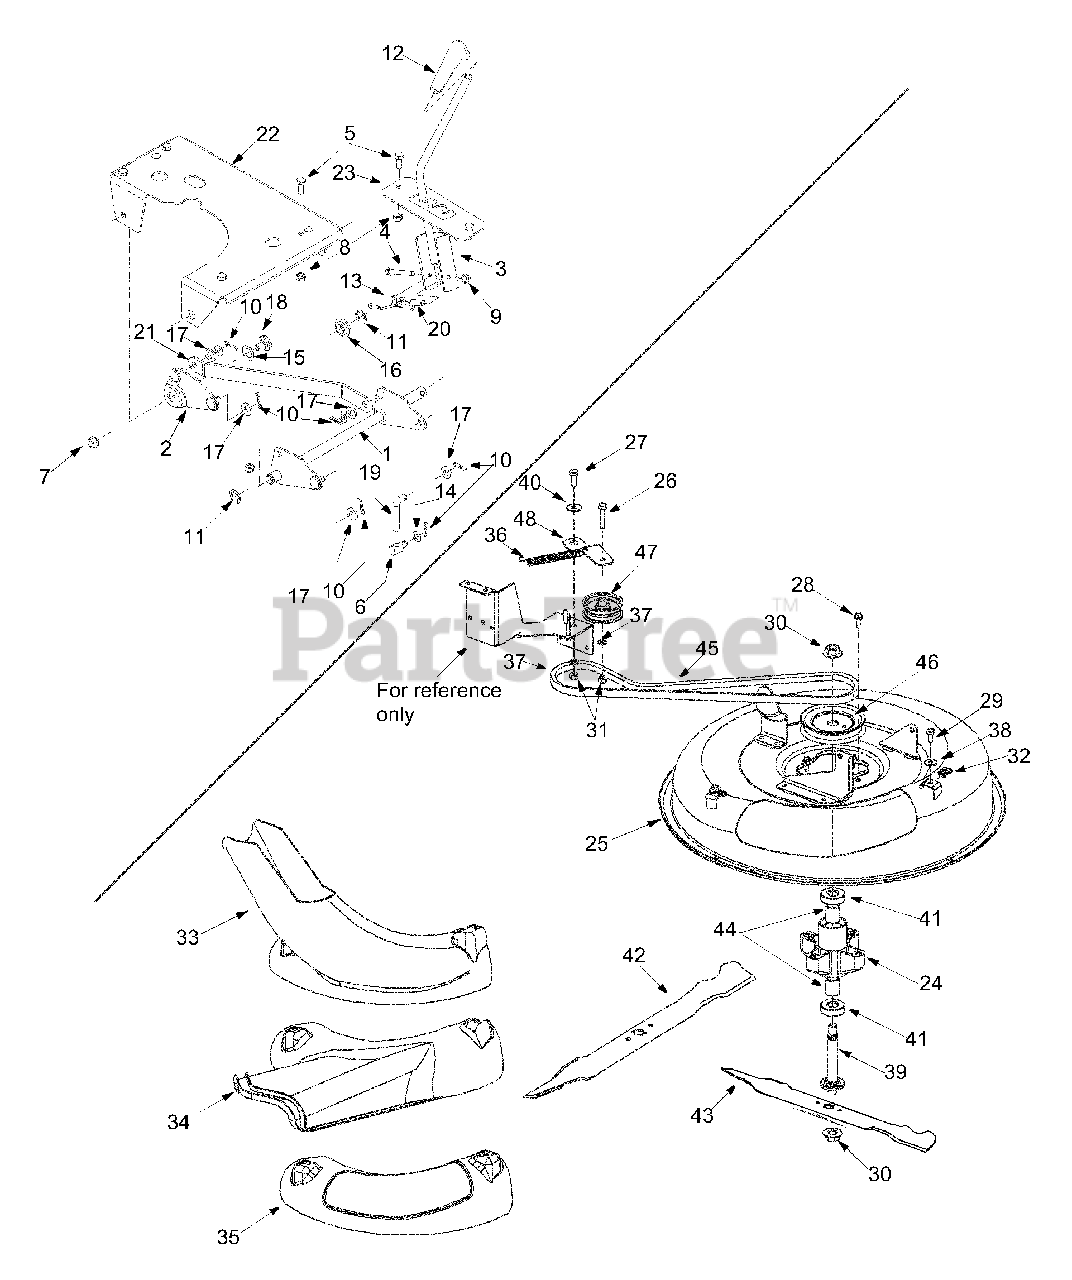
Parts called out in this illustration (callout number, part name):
1	Shift Assembly: Front Lift
2	Pivot Bracket Assembly
3	Bracket Assembly: Lift Handle
4	Hex Bolt 1/4-20 x 2.25
5	Hex Bolt M8-1.25: 20
6	Ferrule
7	Flange Lock Nut 3/8-16
8	Hex Lock Nut M8-1.25
9	Lock Nut 1/4-20
10	Hairpin Clip
11	E-Ring
12	Handle Grip
13	Torsion Spring
14	Thrust Washer .375 x .70 x .030
15	Flat Washer 5/8 x 1.0 x .030
16	Flange Washer .633 x .883
17	Flat Washer .407 x .812 x .135
18	Shoulder Screw .625 x .17: 3/8-16
19	Lift Link
20	Spacer
21	Upper Lift Link Bracket
22	Lift Hanger Bracket
23	Lift Indx. Bracket
24	Spindle Housing
26	Hex Screw 3/8-16 x 1.75
27	Hex Bolt 3/8-16 x 1.0
28	TT Screw 5/16-18 x 0.875
29	Wing Bolt M8-1.25 x 20 mm.
30	Flange Nut 5/8-18
31	Hex Nut 3/8-16
32	Speed Nut M8-1.25
33	Grass Catcher Chute
34	Side-Discharge Chute
35	Mulch Plug
36	Extension Spring
37	Lock Washer
38	Flat Washer 8.4 x 24
39	Spindle Shaft
40	Shoulder Spacer
41	Ball Bearing
42	Blade: Bagging
43	Blade: 3-in-1
44	Spacer
45	Belt: V Type
46	Deck Pulley
47	Flat Idler Pulley
48	Idler Bracket: Deck
